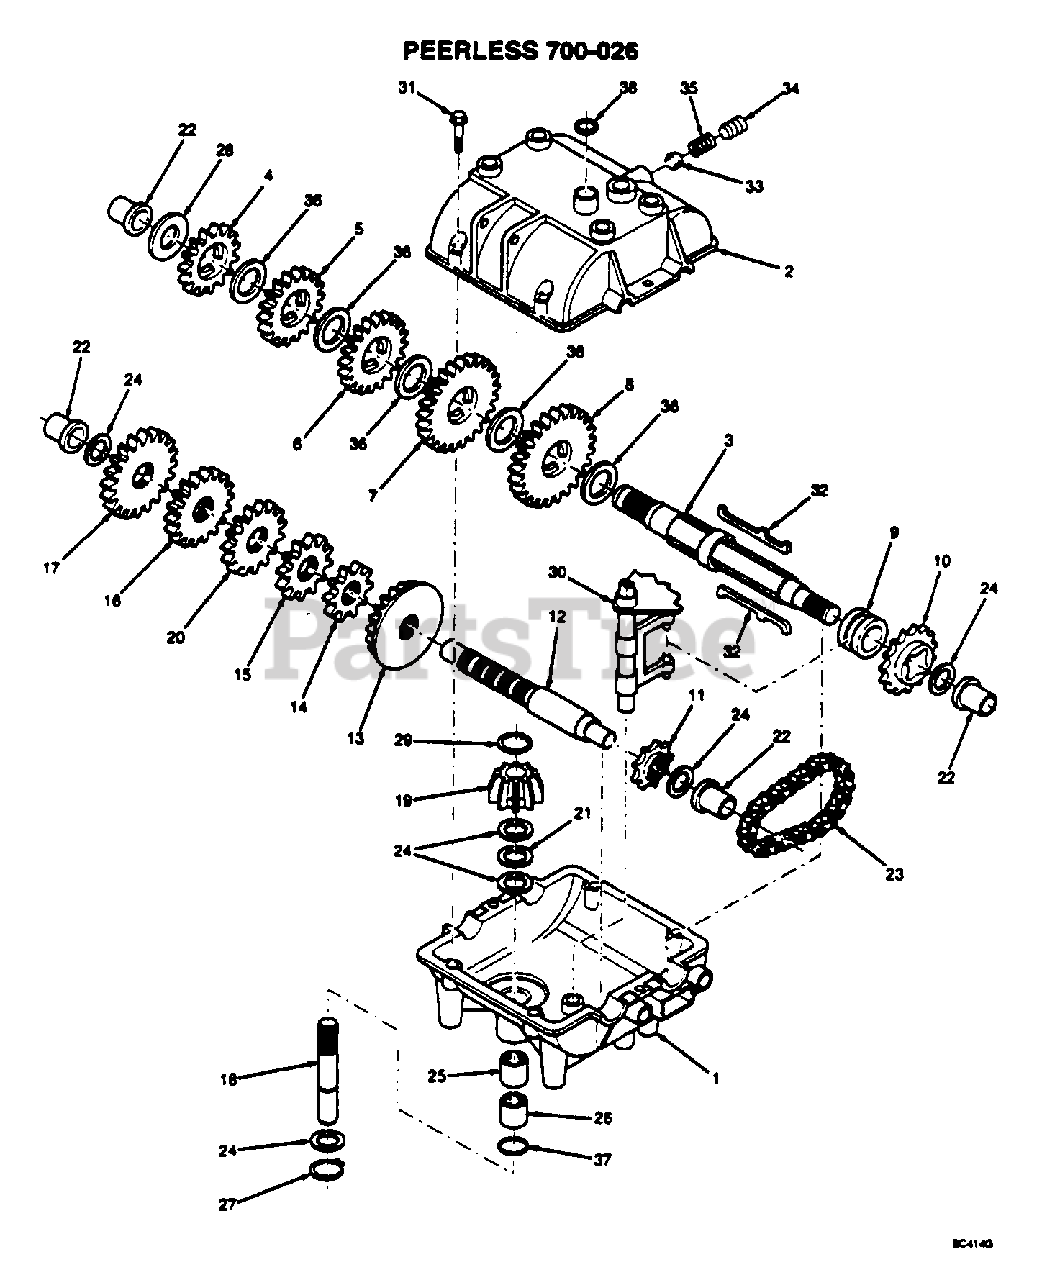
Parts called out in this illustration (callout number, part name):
1	Case, Transmisson
2	Cover, Transmission
3	Shaft, Output & Brake
4	Gear, Spur (25 teeth)
5	Gear, Spur (30 teeth)
6	Gear, Spur (32 teeth)
7	Gear, Spur (35 teeth)
8	Gear, Spur (37 teeth)
9	Collar, Shift
10	Sprocket (18 teeth)
11	Sprocket (9 teeth)
12	Shaft, Counter
13	Gear, Bevel (42 teeth)
14	Gear, Spur (12 teeth)
15	Gear, Spur (15 teeth)
16	Gear, Spur (20 teeth)
17	Gear, Spur (25 teeth)
18	Shaft, Input
19	Bevel Pinion, Input
20	Gear, Spur (18 teeth)
21	Bearing, Thrust
22	Bushing, Flanged
23	Chain, Roller (No.41 chain, 24 links)
24	Washer, Thrust
25	Bearing, Needle
26	Bearing, Needle
27	Ring, Retaining
28	Washer, Thrust
29	Ring, Retaining
30	Rod & Fork Assy., Shift
31	Screw, Flanged Hex Hd Thread, 1/4-20 x 1-1/4"
33	Ball, Steel, 5/16"
34	Screw, Set 3/8-16 x 3/8"
35	Spring
36	Washer, Thrust
37	"O" Ring
38	Seal, Square cut
